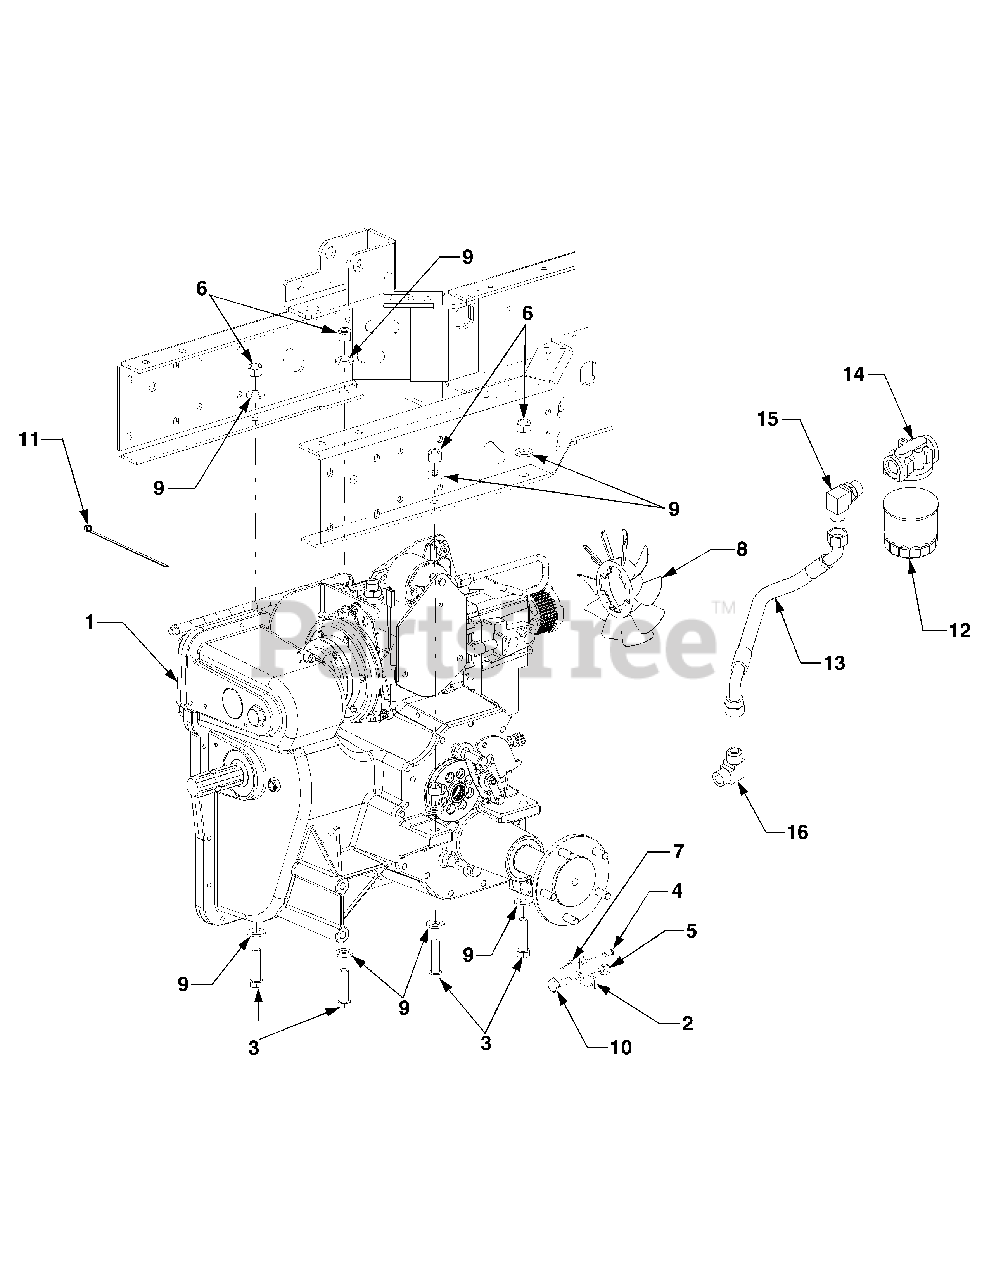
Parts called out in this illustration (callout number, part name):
1	Transmission Assembly
2	Link, Diff Lock Actuator
3	Screw, Hex Cap 1/2-13 x 2.0 GR8
4	Pin, Clevis, .25 x .50
5	Nut. Hex Insert Lock, 3/8-24
6	Nut, Hex Insert Lock, 1/2-13
7	Pin, Internal Cotter
8	Fan, Transmission Cooling
9	Washer, Flat, .531 x .1062 x .134
10	Screw, Shoulder, 1/2 Dia. x .180
11	Tie, Cable
12	Filter, Oil
13	Hose, Filter
14	Adapter, Oil Filter
15	Fitting, 90° Elbow
16	Fitting, 90° Elbow
